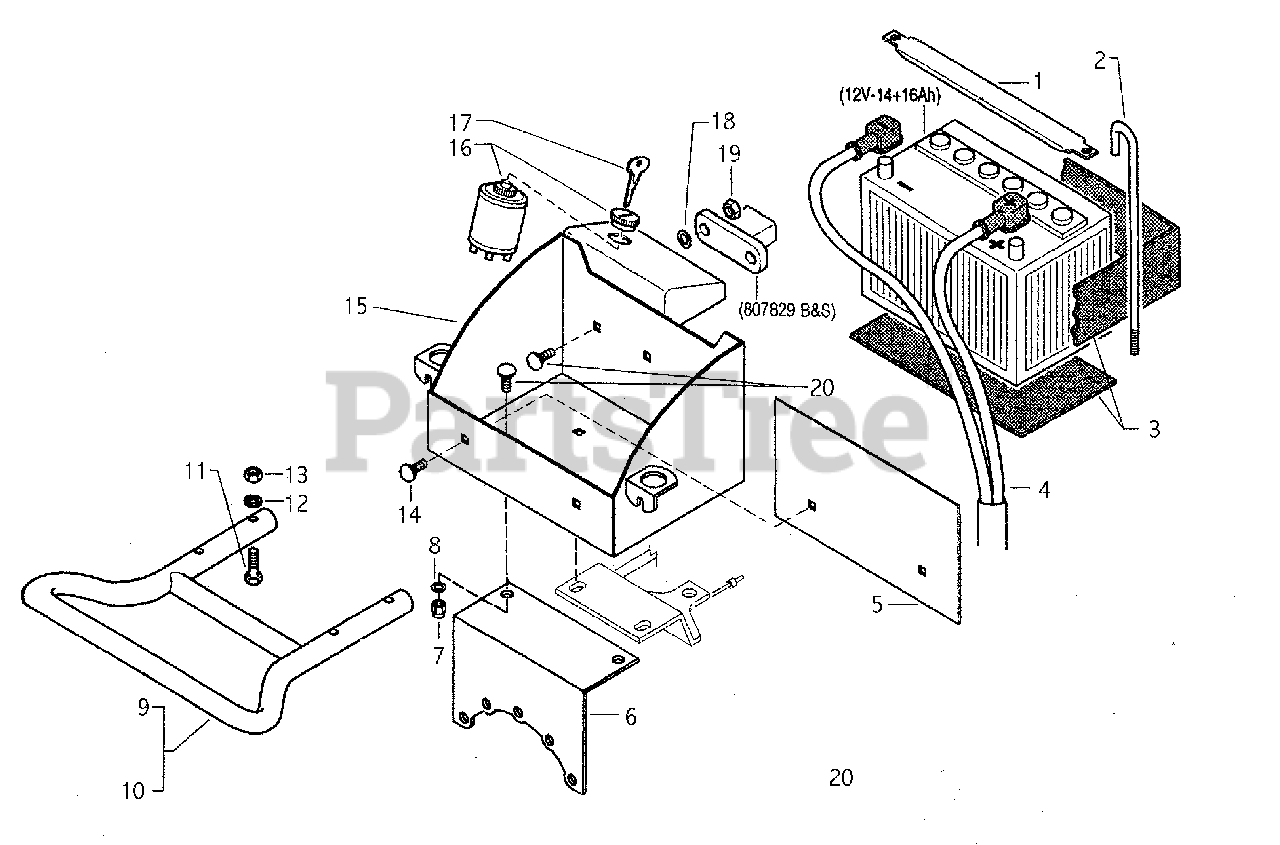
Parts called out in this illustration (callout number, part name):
1	BATTERY BRACKET
2	BATTERY TIEROD
3	BATTERY PADS
4	ELECTRIC START CABLES
9	BUMPER , B&S INTEK 5.5/6.5 HP
10	BUMBER, HONDA GX160
11	SCREW M8X60
12	FLAT WASHER 8.4
13	NUT, SELF LOCKING M8
15	BATTERY SUPPORT
